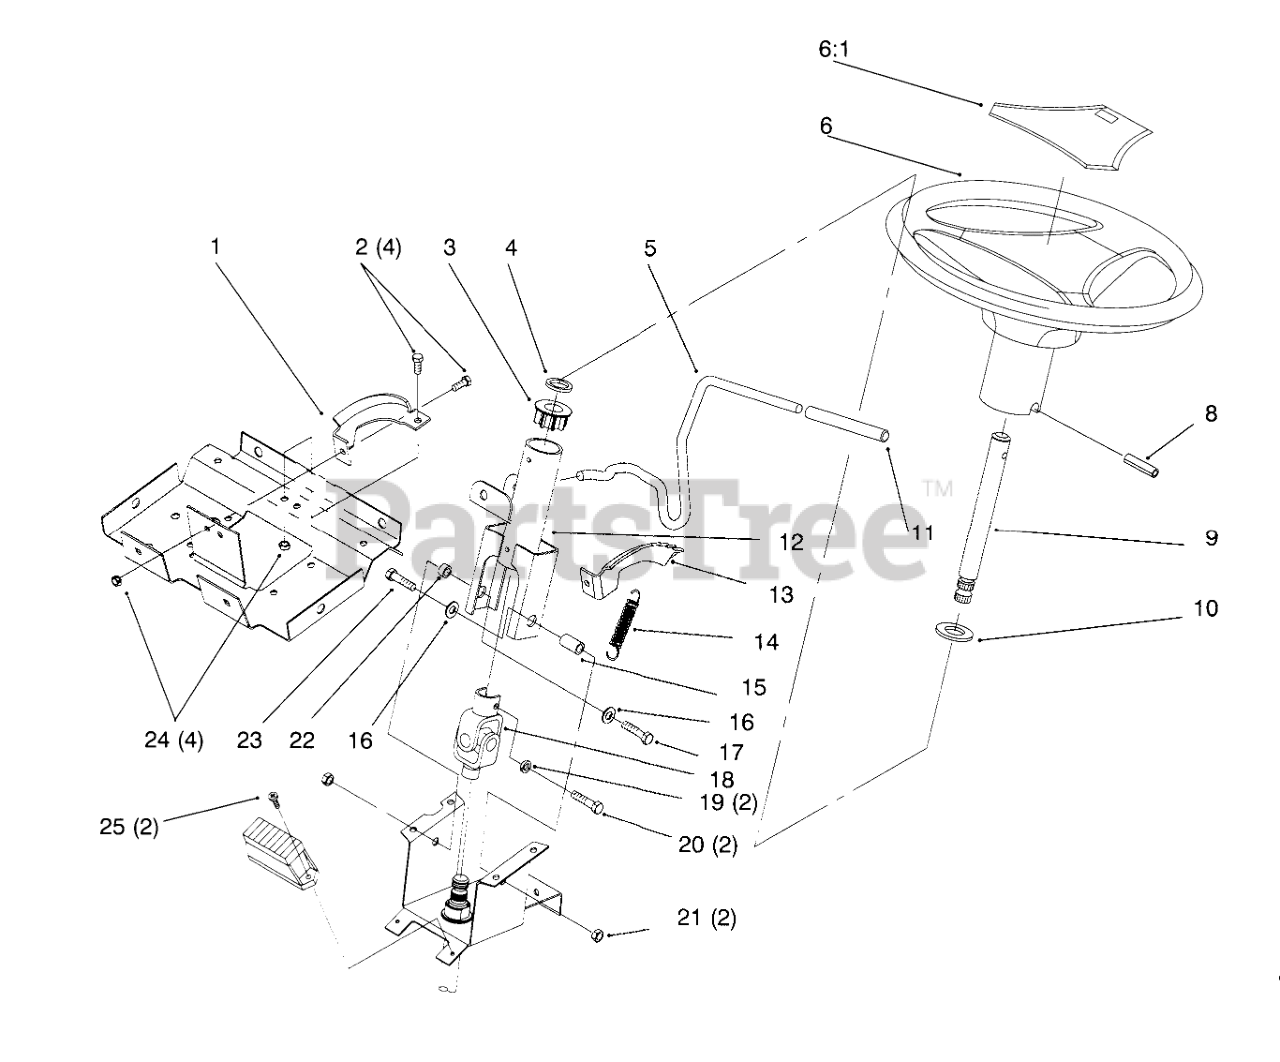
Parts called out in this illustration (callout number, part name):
1	BRACKET-SUPPORT, COLUMN
2	SCREW-HH
3	BUSHING-STEERING, UPPER
4	WASHER-BOWED
5	LEVER-TILT
6	STRG WHL - SOFT TOUCH
8	PIN-ROLL
9	SHORT UPPER STRG SHAFT
10	WASHER-FLAT
11	CAP-ROD, TILT
12	COLUMN ASM
13	BRACKET-DETENT
14	SPRING-EXTENSION
15	SPACER-YOKE
16	WASHER-PLAIN
17	SCREW-HH
18	U-JOINT, STEERING
19	WASHER-LOCK
20	SCREW-CAP, HH
21	NUT-LOCK, NI
22	SPACER-YOKE, RIGHT
23	SCREW-HH
24	NUT-HEX
25	SCREW-PPHTF
